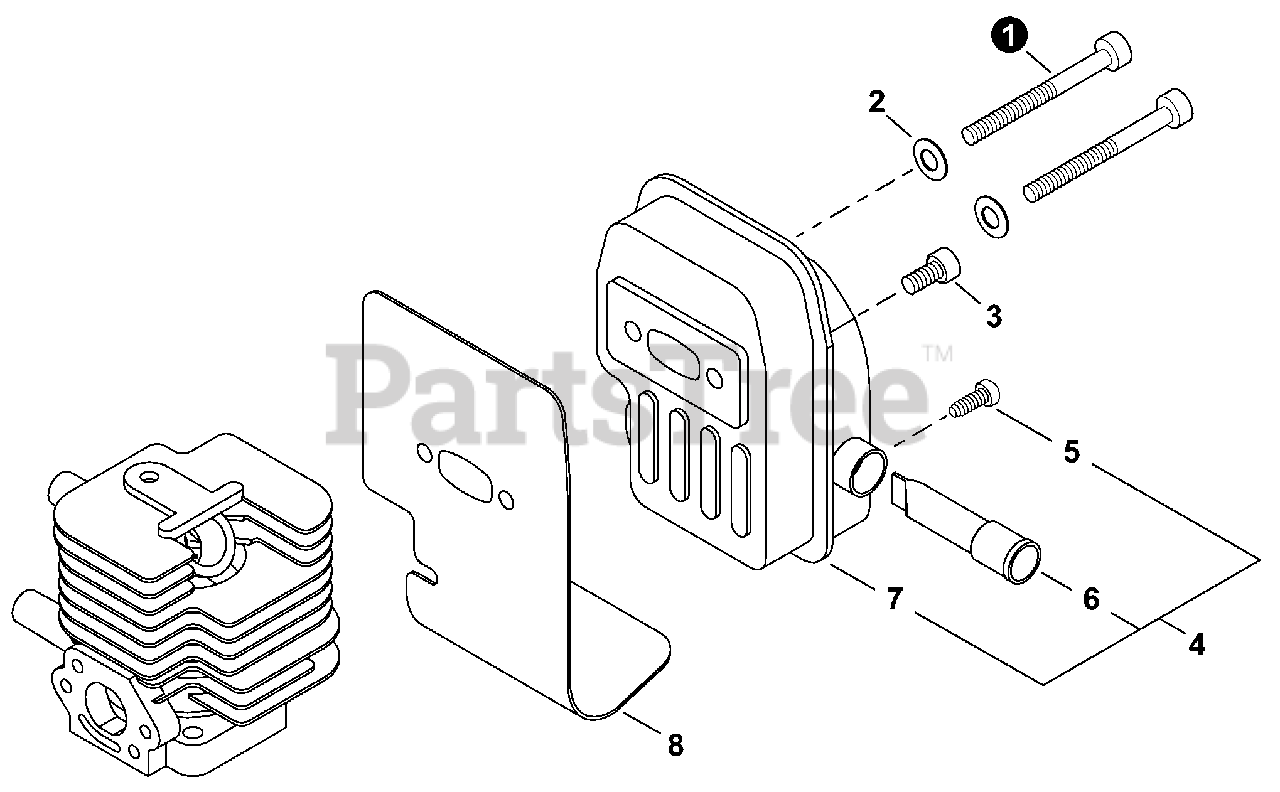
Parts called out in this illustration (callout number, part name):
1	BOLT M5x50
2	WASHER, FLAT 5.5x10x0.8
3	BOLT 5x12
4	MUFFLER ASSY
5	SCREW, TAPPING 3x6
6	SCREEN, SPARK ARRESTER
7	MUFFLER
8	HEAT SHIELD, EXHAUST
